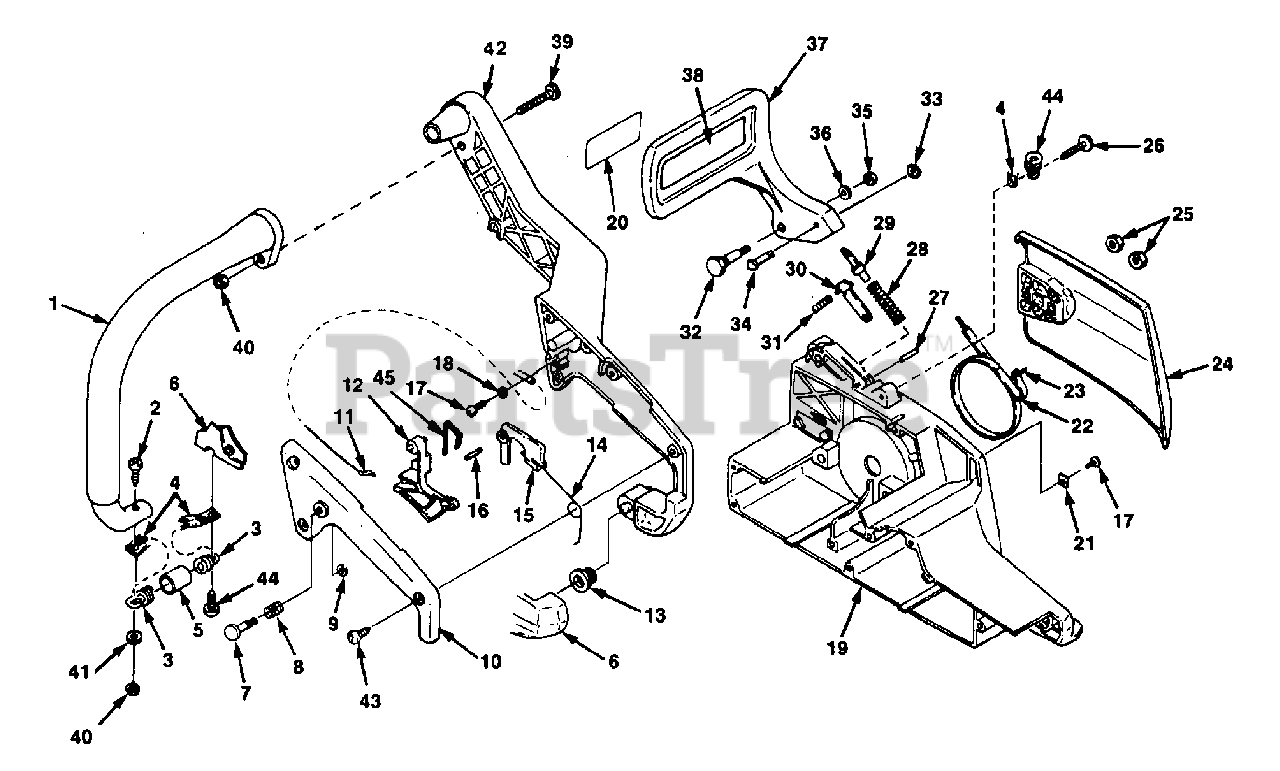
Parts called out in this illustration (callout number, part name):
1	HANDLE BAR
2	SCREW (10-24 x 1/2")
3	SPRING- Extension
4	RETAINER- Spring
5	SLEEVE- Spring
6	HOUSING- Starter side
7	PIN- Throttle lock
8	SPRING- Compression
9	RING- Retaining
10	COVER- Rear handle
11	CABLE- Throttle
12	TRlGGER- Throttle
13	ISOLATOR- Vibration
15	LOCK- Throttle
16	PIN- Dowel
17	SCREW (6-19 x 1/2")
19	HOUSING- Drive side
20	LABLE- Kick back
21	RETAINER- Break band
22	BRAKE BAND ASSEMBLY
24	COVER- Drive case
25	NUT- (5/16 x 18)
26	SCREW- (8-16 x 5/8")
28	SPRING- Compression
29	ADJUSTER- Brake
30	BRAKE LATCH ASSEMBLY
31	SPRING- Coil
32	SCREW- Shoulder
33	RING- Retainer
36	WASHER (Belleville)
37	HAND GUARD ASSY.
38	DECAL- Safety
39	SCREW (10-24 x 1 1/8")
41	WASHER
43	SCREW- (8-16 x 5/8")
44	SPRING
45	SPRING- Trigger
